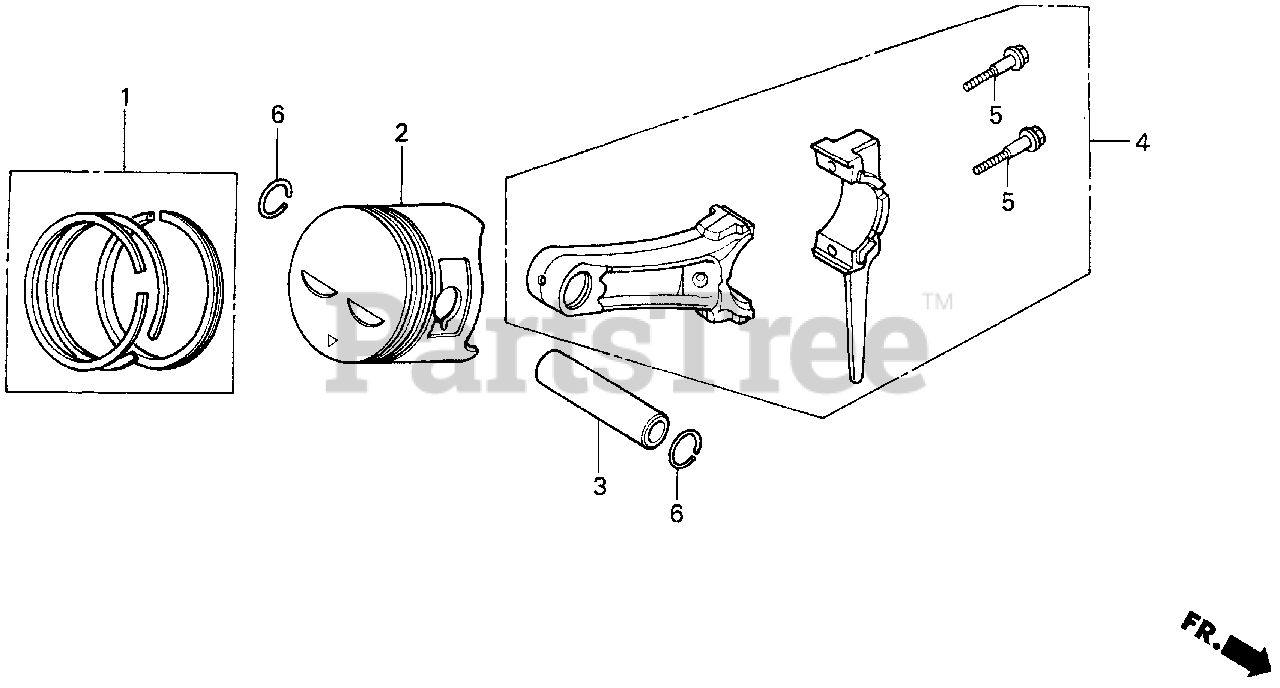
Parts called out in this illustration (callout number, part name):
1	RING SET, PISTON (STD)
1	RING SET, PISTON (OS 0.25)
1	RING SET, PISTON (OS 0.50)
1	RING SET, PISTON (0.75)
2	PISTON (STD)
2	PISTON (OS 0.25)
2	PISTON (OS 0.50)
2	PISTON (0.75)
3	PIN, PISTON
4	ROD ASSY., CONNECTING (STD)
4	ROD ASSY., CONNECTING (US 0.25)
5	BOLT, CONNECTING ROD
6	CLIP, PISTON PIN (18MM)
